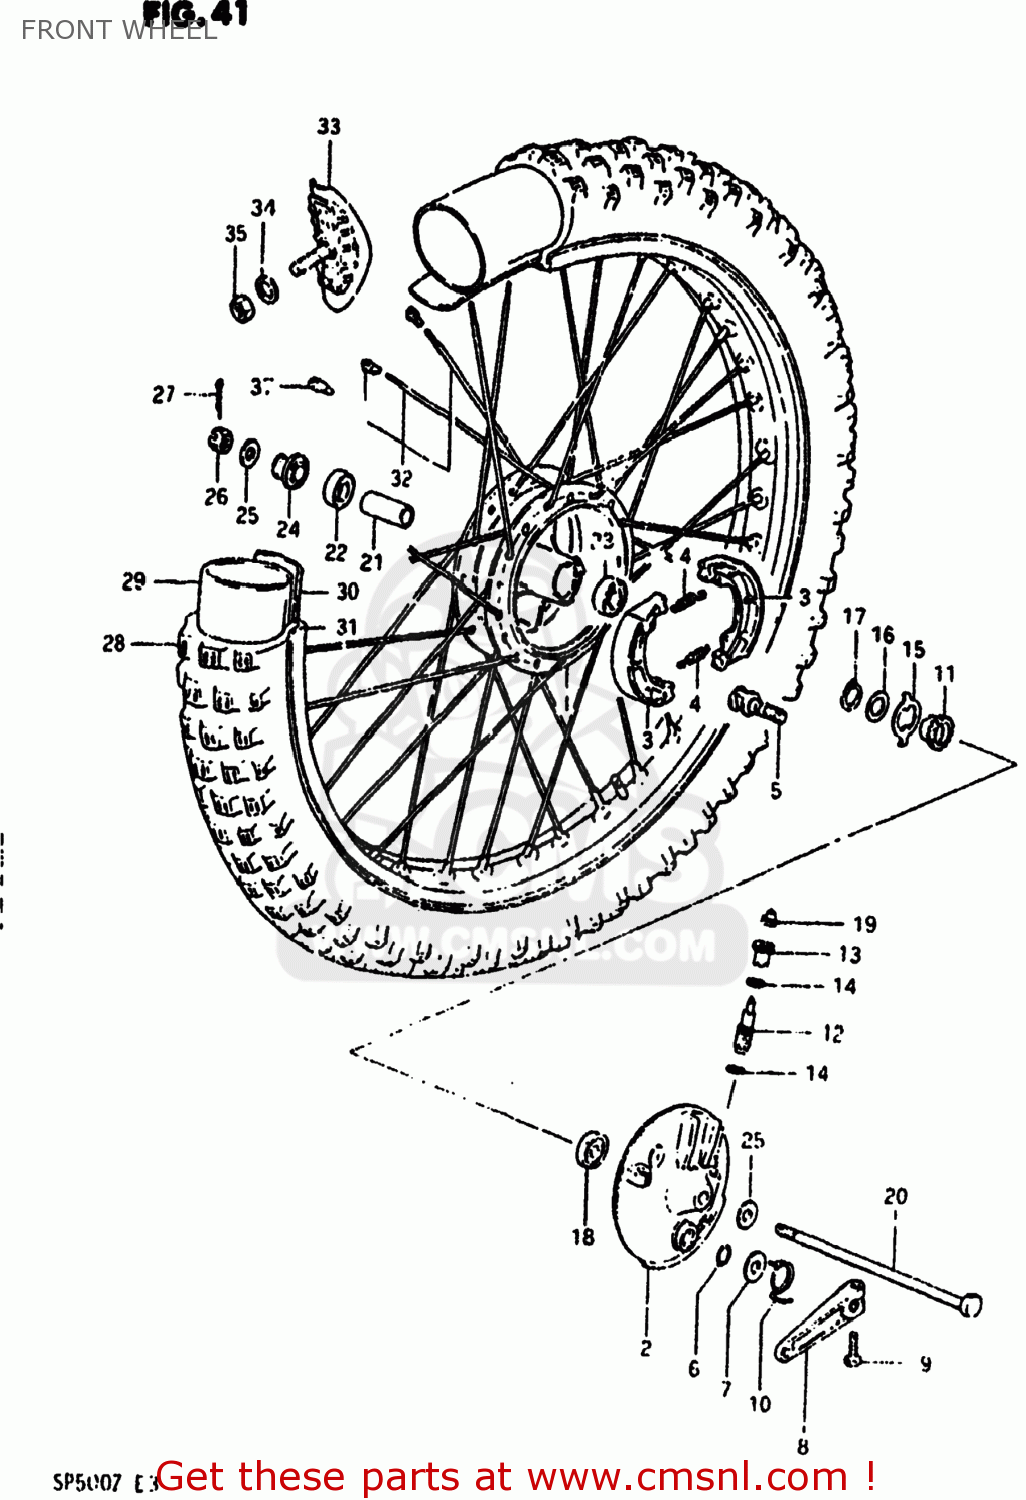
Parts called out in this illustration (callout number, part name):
1	DRUM,FRONT HUB
2	PANEL,FRONT BRAKE
3	SHOE,BRAKE
4	SPRING
5	CAM,FRONT BRAKE
6	O-RING,BOSS
7	WASHER (15X24X1.6)
8	LEVER,FRONT BRAKE CAM
9	BOLT
10	SPRING
11	GEAR,SPEEDOMETER
12	PINION,SPEEDOMETER
13	BUSHING,SPEEDOMETER PINION
14	WASHER (5.1X9X0.4)
15	DRIVER,SPEEDOMETER GEAR
16	WASHER(22.5X27X1)
17	CIRCLIP
18	SEAL,OIL(26X38X4)
19	SEAL,OIL(6X10X3)
20	AXLE,REAR
21	SPACER (12.6X19X52)
22	BEARING, RH
23	BEARING
24	SPACER,FRONT AXLE,RIGHT
25	WASHER
26	NUT, REAR AXLE
27	COTTER PIN
28	TIRE 3.00-21
29	TUBE
30	PROTECTOR,WHEEL,INNER
31	RIM,FRONT WHEEL
32	SPOKE SET,FRONT
33	STOPPER,BEAD
34	WASHER
35	NUT
36	BALANCER,WHEEL (50G)
